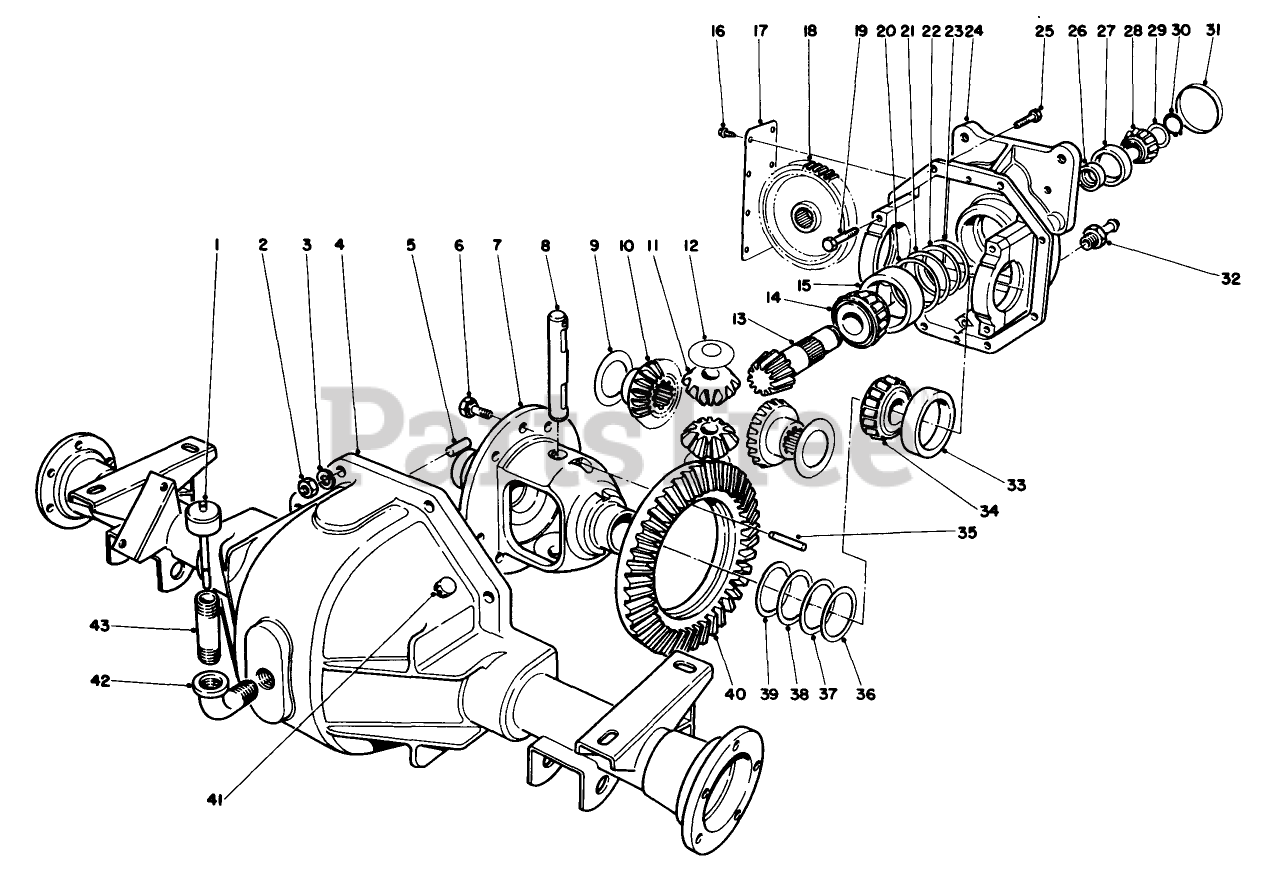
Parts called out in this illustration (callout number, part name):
1	DIPSTICK
2	NUT-HEX
3	WASHER-LOCK
4	HSG TUBE & PAD LWR B
5	PIN-DOWEL
6	SCREW-GEAR, DRIVE
7	CASE-DIFFERENTIAL
8	SHAFT-MATE, PINION
9	WASHER-THRUST
10	GEAR-DIFFERENTIAL
11	PINION-DIFFERENTIAL
12	WASHER-THRUST, PINION
14	BEARING-ROLLER, CONE TAPER
15	BEARING-TAPER, CUP
16	SCREW
17	COVER-GEAR
18	Gear-Spur
19	SCREW-HH
20	SHIM-PINION (.003)
21	SHIM-PINION (.005)
22	SHIM-PINION (.010)
23	SHIM-PINION (.030)
24	Assembly-Housing, Upper (Incl. Ref. #19)
25	SCREW-HH
26	SPACER-BEARING
27	BEARING-CUP
28	CONE-BEARING
29	SHIM-BEARING, FRONT
30	RING-SNAP
31	PLUG-CUP
32	FTG - HYD, STRAIGHT
33	CUP-BEARING, ROLLER
34	BEARING-ROLLER, CONE
35	PIN-ROLL
36	SHIM-BEARING, DIFFERENTIAL (.003)
37	SHIM-BEARING, DIFFERENTIAL (.005)
38	SHIM-BEARING, DIFFERENTIAL (.010)
39	SHIM-BEARING, DIFFERENTIAL (.030)
40	Gear-Ring
41	VENT TUBE ASM
42	FITTING-ELBOW-90
43	PIPE NIPPLE
